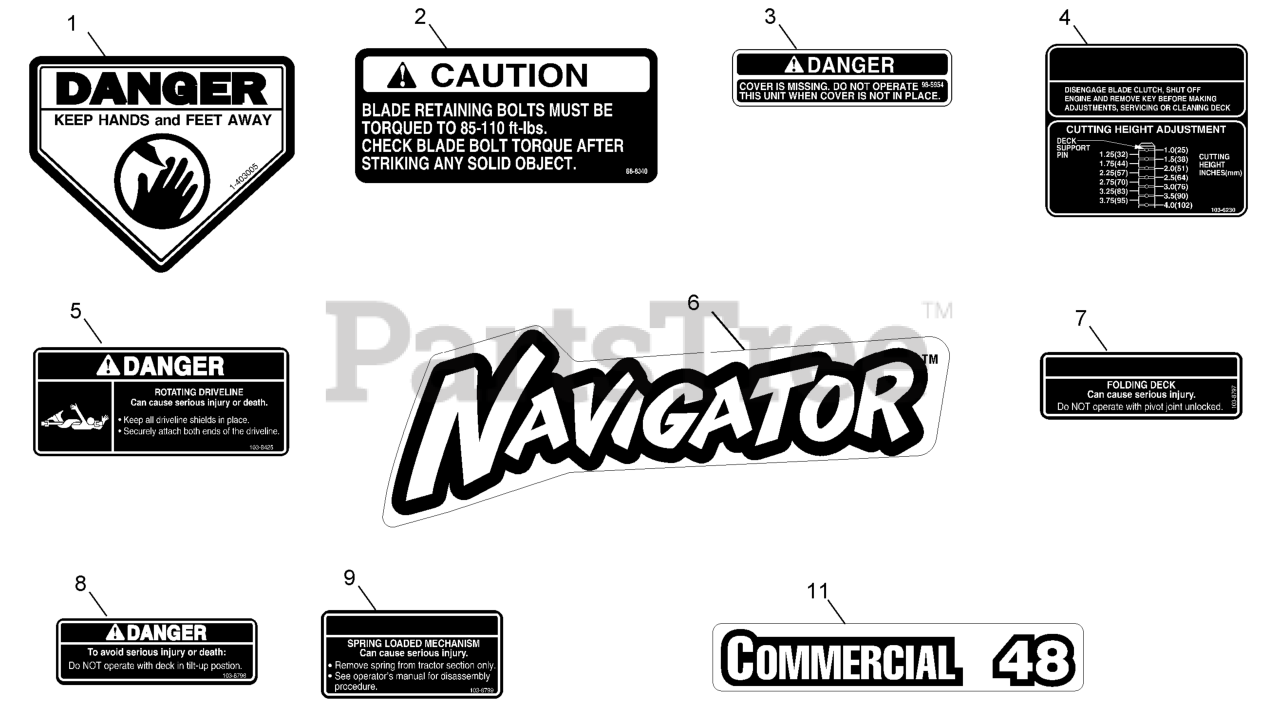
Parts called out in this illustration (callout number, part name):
1	DECAL-DANGER
2	DECAL-TORQUE
3	DECAL-COVER, MISSING
5	DECAL-DRIVELINE
6	DECAL,NAVIGATOR MODEL
7	DECAL-FOLDING DECK
8	DECAL-DANGER
9	DECAL-SPRING
11	DECAL,COMMERCIAL 48
